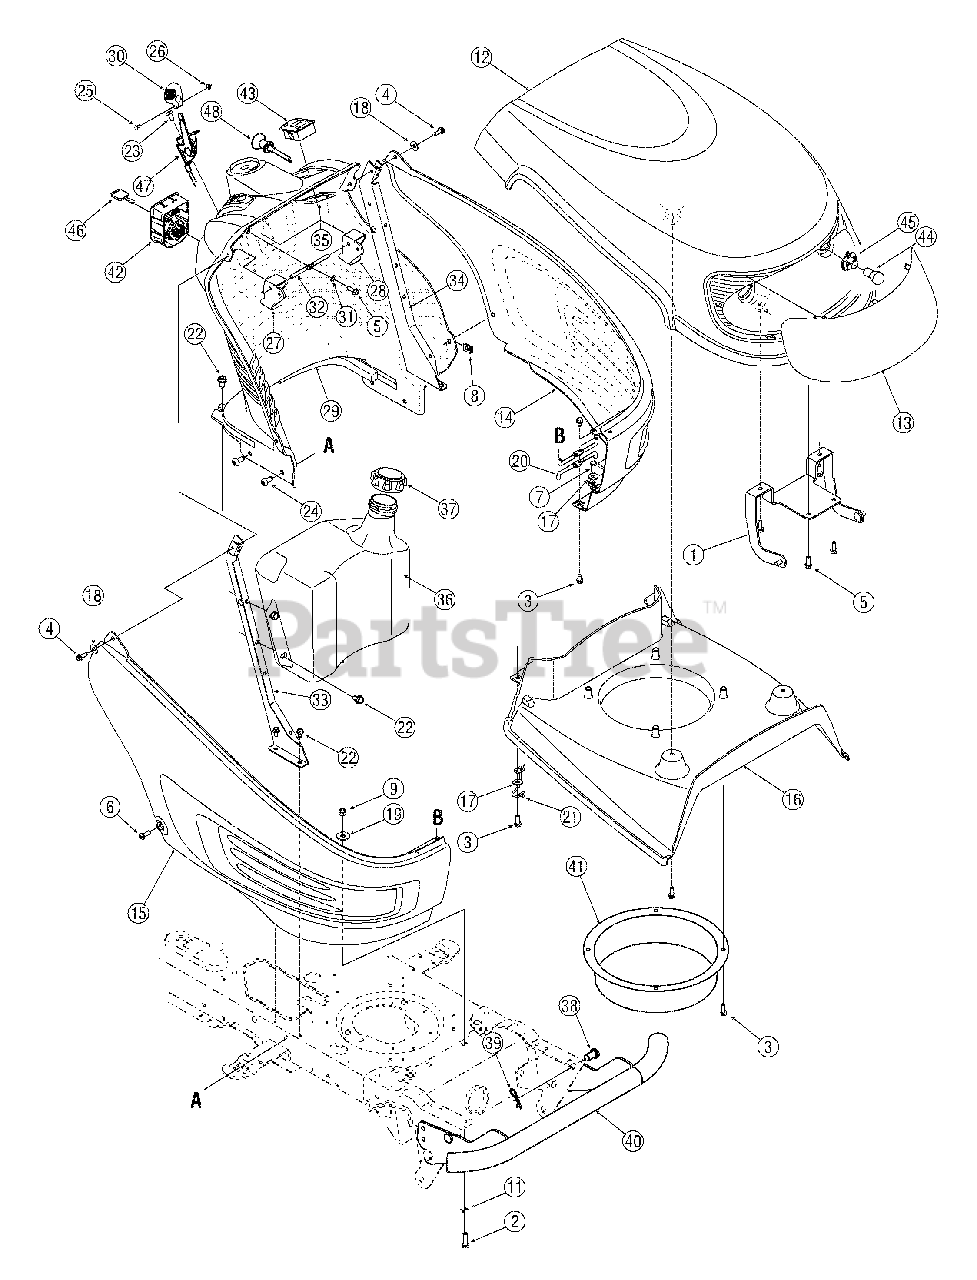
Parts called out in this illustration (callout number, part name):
3	Screw, 1/4-20, 0.500
4	Screw, 1/4-20, 0.750
5	Screw, 1/4-15, 0.750
6	Screw, Machine, 1/4-20, 0.750
7	Hex Screw, 1/4-20, .75, Gr5
8	Nut, Clip, 1/4-20
9	Nut, Flange Lock, 5/16-18, Grf, Nylon
10	Nut, Flange Lock, 1/4-20, Grf, Nylon
11	Nut, Speed, .3125 ID
12	Hood
13	Lens
14	Side Panel, LH
15	Side Panel, RH
16	Plenum, Red
17	Washer, Flat, .28 x .74 x .063
18	Washer, Flat, .283 x .75 x .030
19	Washer, Flat, .344 x 1.0 x .063
20	Support, Side Panel
21	Rod, Hood Latch
22	Screw, 5/16-12, 0.750
23	Screw, 1/4-14, 0.625
24	Screw, 5/16-18, 0.750
25	Screw, Machine, #8-32, 0.375
26	Nut, Hex, #8-32
27	Brake Lever
28	Cruise Control Lever
29	Dash Panel (Models w/ Electric PTO)
29	Dash Panel (Models w/ Manual PTO)
30	Control Knob
31	Washer, Flat, .281 x .50 x .063
32	Rod, Brake / Cruise Pivot
35	Retainer Bracket, PTO Switch
36	Fuel Tank, 3 Gal.
36	Fuel Tank, 2 Gal.
37	Fuel Cap (Fits either fuel tank)
38	Pin, Clevis, .50 x .78
39	Pin, Click, .092 x 1.64
40	Bumper
41	Bellow
42	Ignition Switch Module
43	Systems Indicator Monitor w/ Hour Meter
44	Miniature Lamp, 12V
45	Socket, Lamp
46	Key, Ignition
46	Key w/ Plastic Cover, Ignition
47	Throttle Cable, 39"
48	Choke Knob w/ Cable, 37.5"
